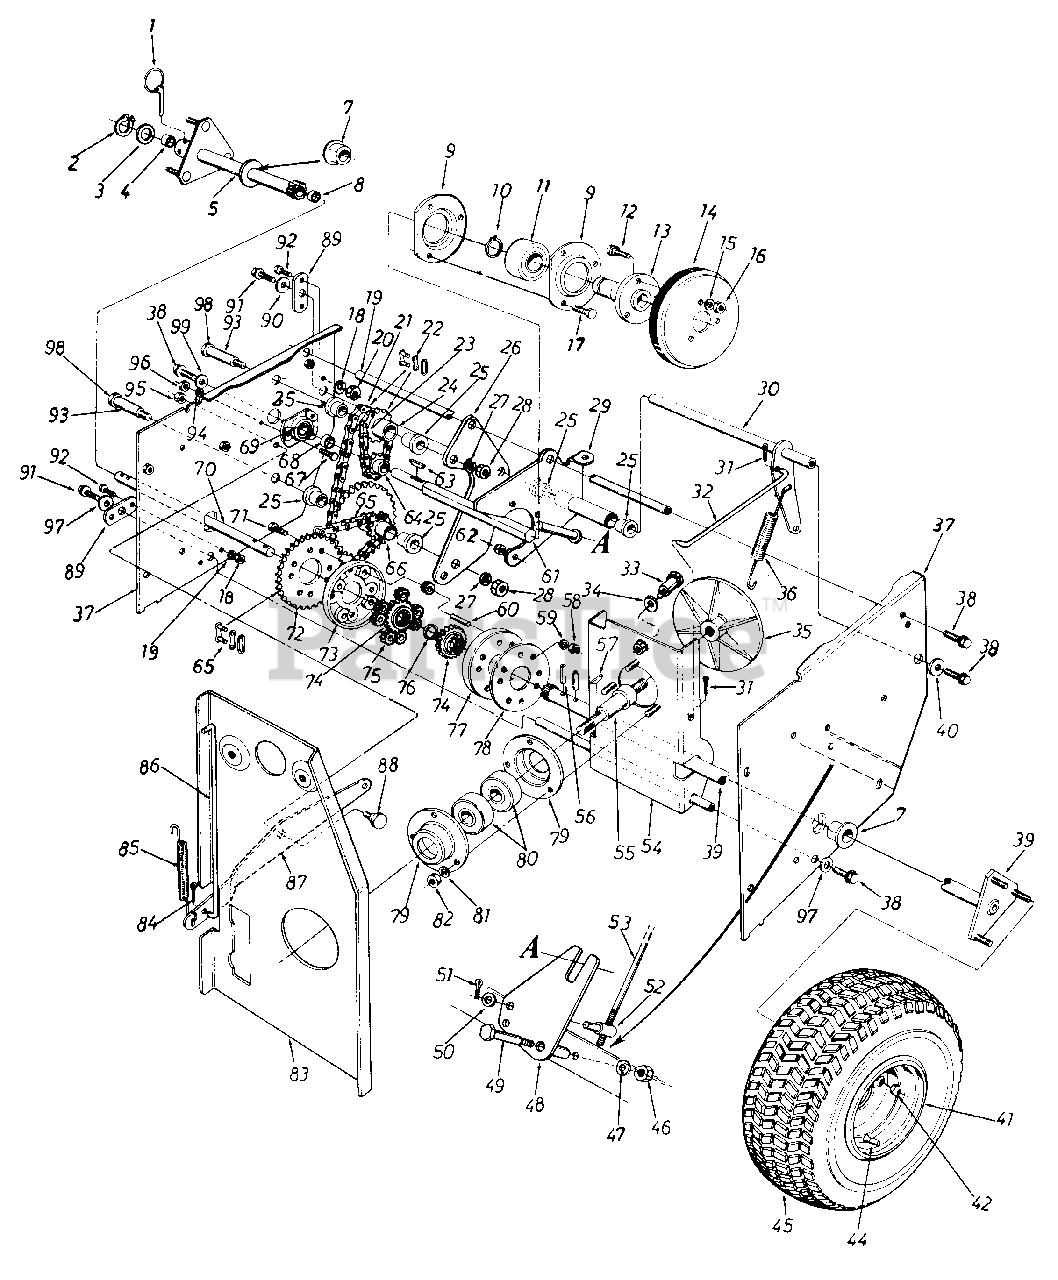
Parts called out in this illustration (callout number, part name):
1	Klick Pin 1/4" Dia. x 1.75"
2	Snap Ring .625" Shaft
3	Fl-Wash. .62" I.D. x 1.25"
4	Sleeve Brg.
5	Differential Tubing Ass'y.-R.H.
7	Flange Brg. w/Flats 1" I.D.
8	Sleeve Brg.
9	Bearing Housing
10	Snap Ring-1.00" Dia.
11	Ball Brg. .25MM x 52MM x 15MM Thk.
12	Hex Sems Bolt 5/16-18 x .75" Lg.*
13	Friction Wheel Adapter
14	Friction Wheel Ass'y.
15	L-Wash. 5/16" I.D.*
16	Hex Nut 5/16-18 Thd.*
17	Hex Bolt 1/4-28 x .62" Lg.*
18	L-Wash. 1/4" I.D.*
19	Sliding Support Axle
20	Hex Nut 1/4-20 Thd.*
21	#41 Chain-1/2" Pitch x 43 Links
22	Master Link
23	#41 Chain-1/2" Pitch x 19 Links
24	9 and 14 Teeth Sprocket Hub Ass'y.
25	Flange Brg. .630" I.D.
28	Hex L-Jam Nut 3/8-24 Thd.
29	Sliding Brkt. Ass'y.
30	Drive Clutch Brkt. Ass'y.
31	Inter. Cot. Pin 5/16" Dia.
32	Drive Clutch Rod 7.38" Lg.
33	Shld. Bolt
34	Bell-Wash. .44" I.D. x .88"
35	Aluminum Drive Plate
36	Extension Spring 4.31" Lg.
37	Frame Ass'y.
38	Hex L-Bolt 5/16-18 x .62"
39	Differential Shaft Ass'y.
40	Fl-Wash. .345" I.D. x .75"
41	Rim Only-16"
42	Cone Nut 3/8-24 Thd.
44	Tubeless Air Valve
45	Wheel Ass'y. Comp. 16 x 6.5
46	Hex Jam Nut 3/8-16 Thd.
47	L-Wash. 3/8" I.D.*
50	Fl-Wash. .344" I.D. x .62"
51	Cotter Pin 3/32" Dia. x .75"
52	Adjustment Ferrule
53	Shifting Rod
56	H-Spring Pin Spiral 3/16" Dia. x 1.25" Lg.
57	#61 Hi-Pro Key 3/16 x 5/8" Dia.
58	Hex Nut 1/4-28 Thd.
59	L-Wash. 1/4" I.D.
60	Differential Pin
61	Hex Shaft
62	Hex L-Nut 1/4-28 Thd.
63	#9 Hi-Pro Key 3/32 x 5/8" Dia.
64	8 Teeth Sprocket
65	#420 Chain-.50 Pitch x 37 Links
66	9 and 32 Teeth Sprocket Hub Ass'y.
67	Hex Bolt 1/4-20 x .62" Lg.*
68	Spacer .51" I.D. x .69" O.D.
69	Ball Bearing
70	Differential Connecting Shaft
71	Hex Bolt 1/4-28 x 1.75" Lg.
72	28 Teeth Sprocket
73	Differential Housing
74	20 Tooth Spur Gear
75	9 Tooth Spur Gear
76	Fl-Wash. .62" I.D. x 1.25"
77	Differential Housing
78	Differential Hsg. Support Plate
79	Bearing Housing
80	Ball Brg. .787" I.D. x 1.85"
81	L-Wash. 5/16" I.D.
82	Hex Nut 5/16-18 Thd.
83	Engine Brkt. Ass'y.
84	Inter. Cotter Pin 5/16" Dia.
85	Extension Spring 3.18" Lg.
86	Auger Clutch Rod .31" Dia. x 10.62" Lg.
87	Auger Clutch Brkt.
88	Shld. Bolt .625" Dia. x .170"
89	Pivot Axle Brkt.
90	Fl-Wash. .345" I.D. x .75"
91	Hex L-Bolt 5/16-18 x .62"
92	Hex Bolt 1/4-20 x .62" Lg.
93	Sprocket Hub Tubing 1.88"
94	L-Wash. 1/4" I.D.
95	Hex Cent. L-Nut 3/8-16 Thd.
96	Hex Nut 1/4-20 Thd.
97	Fl-Wash. .344" I.D. x .875"
98	Hex Bolt 3/8-24 x 2.75" Lg.
99	Bell-Wash. .345" I.D. x .88"
